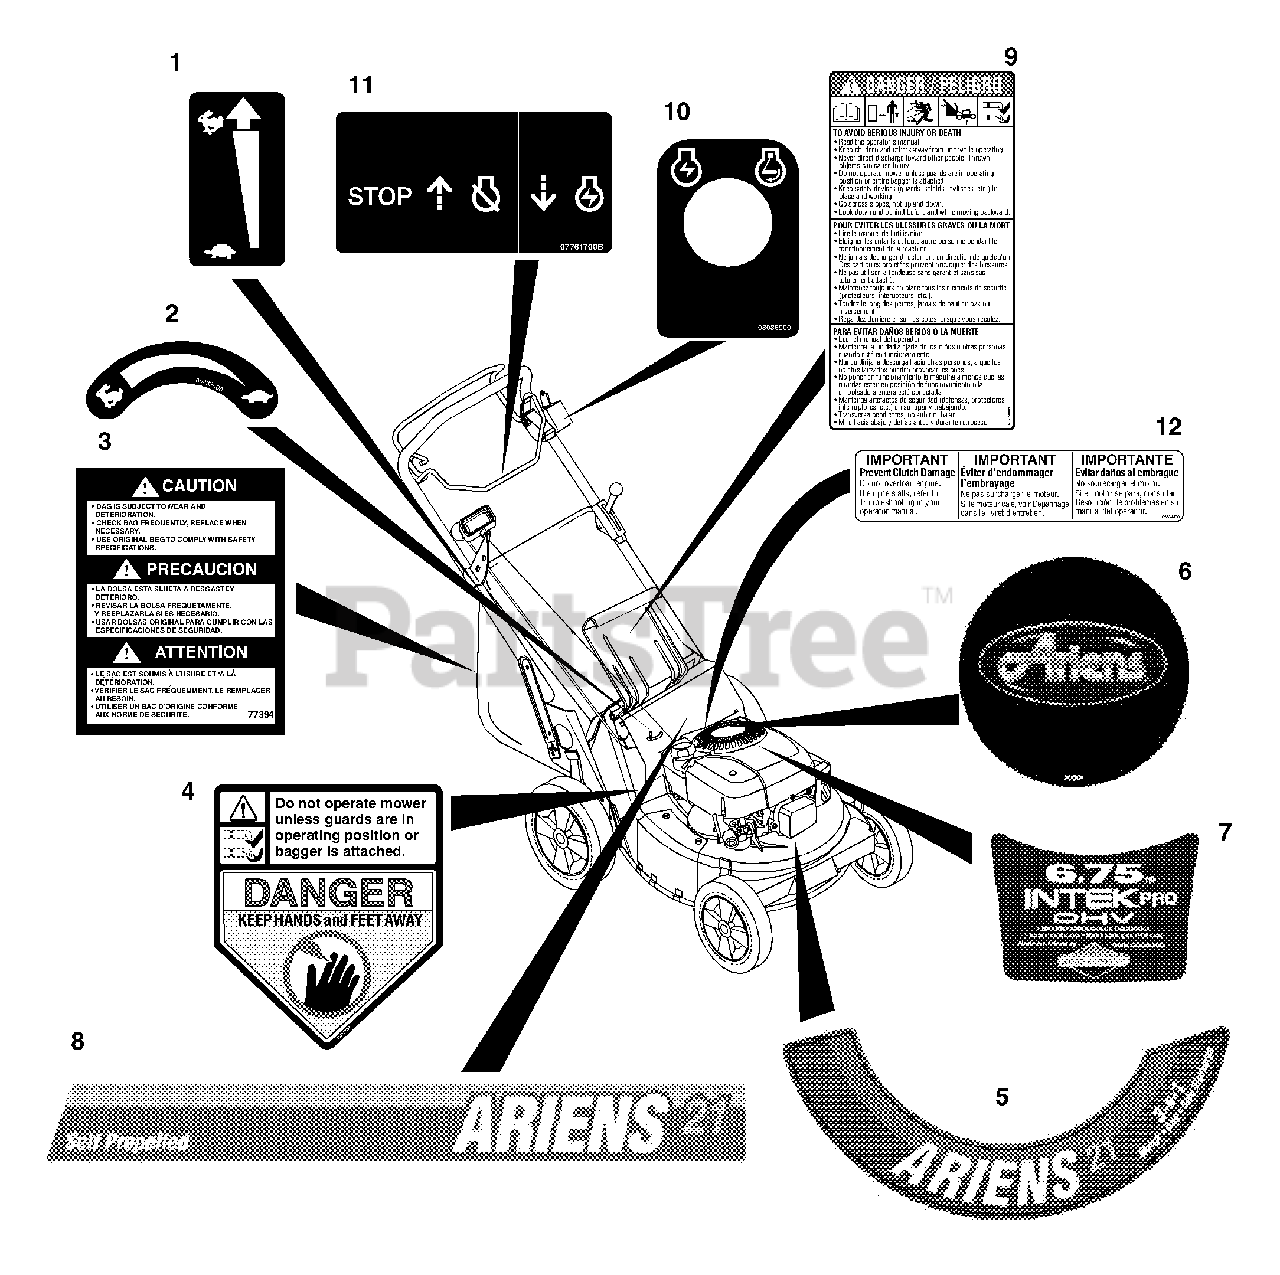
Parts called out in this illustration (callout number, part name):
1	DECAL-SPEED CONTROL
2	DECAL, TURTLE & RABBIT
3	LABEL - BAGGER 21"
4	DECAL, CPSC DANGER
5	DECAL, ARIENS DECK
6	DECAL, ROUND ARIENS B&S
7	DECAL, ARIENS INTEKPRO 6.75
8	DECAL, DRIVE COVER SP
9	DECAL, BILINGUAL DANGER
10	DECAL, KEYSWITCH LM 2-POS
11	DECAL - ENGINE CONTROL
12	DECAL, BBC INSTRUCTION
